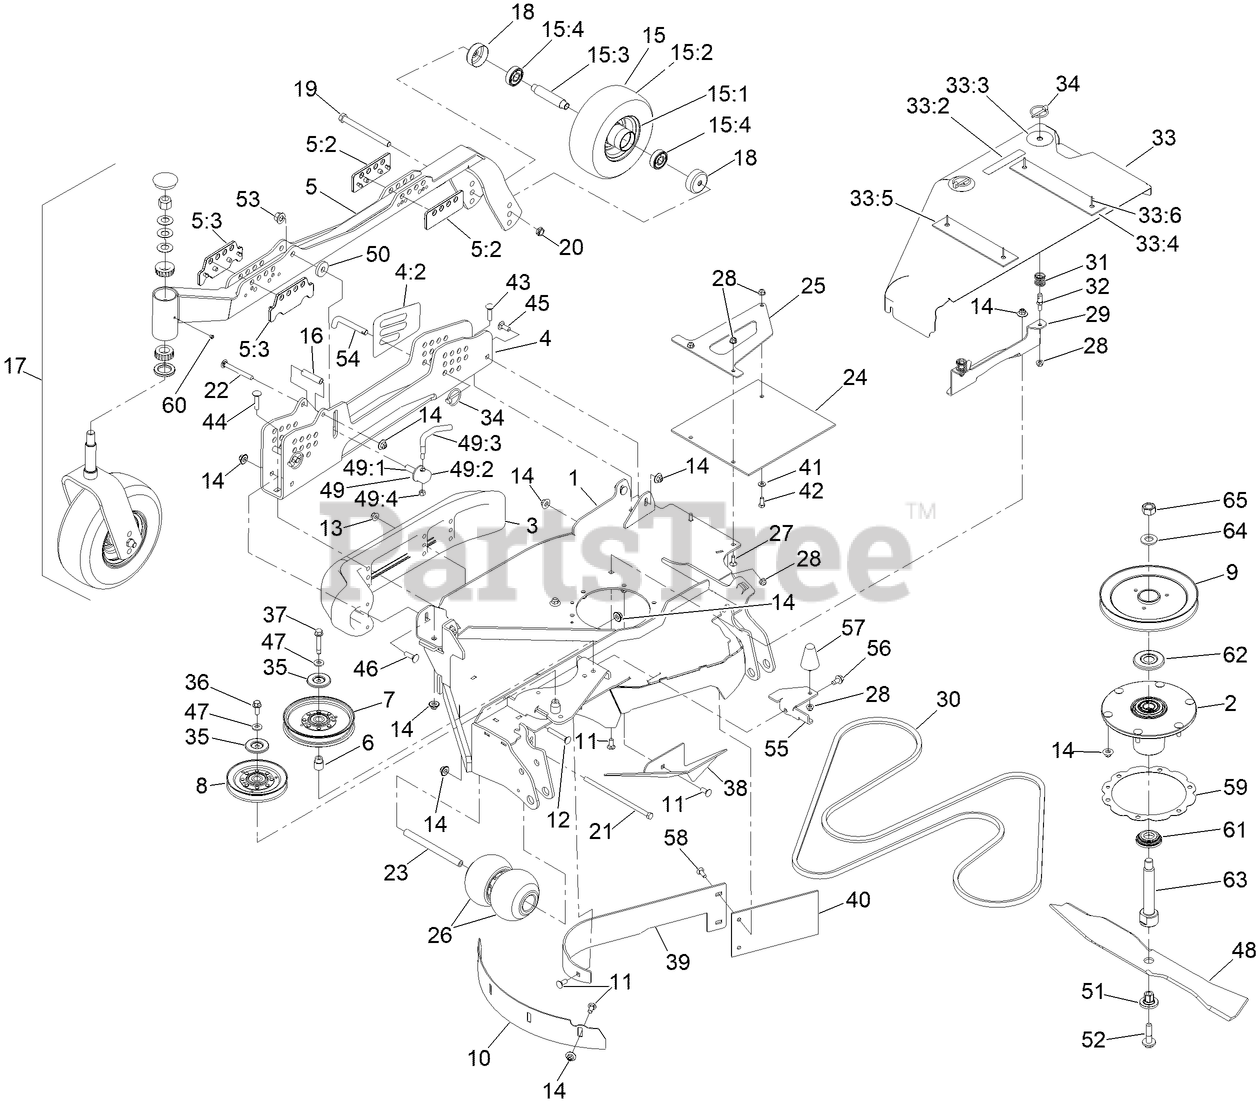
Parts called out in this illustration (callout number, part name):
1	ASM-DECK RH WING 96T
2	SPINDLE ASM
3	SKID-BUMPER, DECK
4	ASM-CHANNEL, HOC RH W/DECALS
4:2	DECAL-HEIGHT OF CUT, RH
5	ASM-RH GAUGE WHEEL ARM
5:2	PLATE-GUIDE, REAR
5:3	PLATE-GUIDE, FRONT
6	BUSHING-IDLER
7	IDLER-PULLEY
8	IDLER-V
9	SHEAVE-DRIVE, BLADE
10	BAFFLE-DEPTH, RH
11	BOLT-CARR
12	SCREW-CARR
13	NUT-HF, NI
14	NUT-FLANGE, NI
15	WHEEL AND TIRE ASM
15:1	WHEEL
15:3	AXLE-CASTER
15:4	BEARING
16	SPACER
17	CASTER WHEEL ASM
18	GUARD, SEAL
19	SCREW-HH
20	NUT-HEX
21	SCREW-HH
22	SCREW-CARR
23	SPACER-WHEEL
24	GUARD-TIRE
25	SUPPORT-FLAP, RH
26	ROLLER-SCALP, ANTI
27	SCREW-CARR
28	NUT-HF, NI
29	BRACKET-SHIELD MOUNT, OUTER
30	BELT-V
31	SPRING
32	PIN, SPRING
33	RH WING SHIELD ASM
33:2	DECAL-NO STEP
33:3	DECAL-SCRATCH COVER
33:5	PLATE-FRONT
33:6	RIVET-POP
34	PIN-LYNCH
35	SHIELD-DUST
36	SCREW-HHF
37	SCREW-HHF W/ PATCH
38	BAFFLE-DEFLECT, RH
39	BAFFLE-DOGLEG, RH
40	FLAP-RUBBER
41	WASHER-PLAIN
42	SCREW-HH
43	SCREW-CARR
44	SCREW-CARR
45	BOLT-CARR
46	BOLT-CARR
47	WASHER-BELLEVILLE
48	BLADE-24.50 MULCH
49	LEVER ASM
49:1	SCREW-LOCK
49:2	CAP-LOCK
49:4	NUT-LOCK, NI
50	WASHER
51	BUSHING-HEX
52	SCREW-SEMS
53	NUT-LOCK
54	PIN-HOC
55	BRACKET-COVER RETAINER
56	SCREW-HWH
57	BUMPER-RUBBER
58	SCREW-CARR
59	RING-SPACER, HOUSING
61	GUARD-BOTTOM
62	GUARD-BEARING, TOP
63	SHAFT-SPINDLE
64	WASHER
65	NUT-HEX
